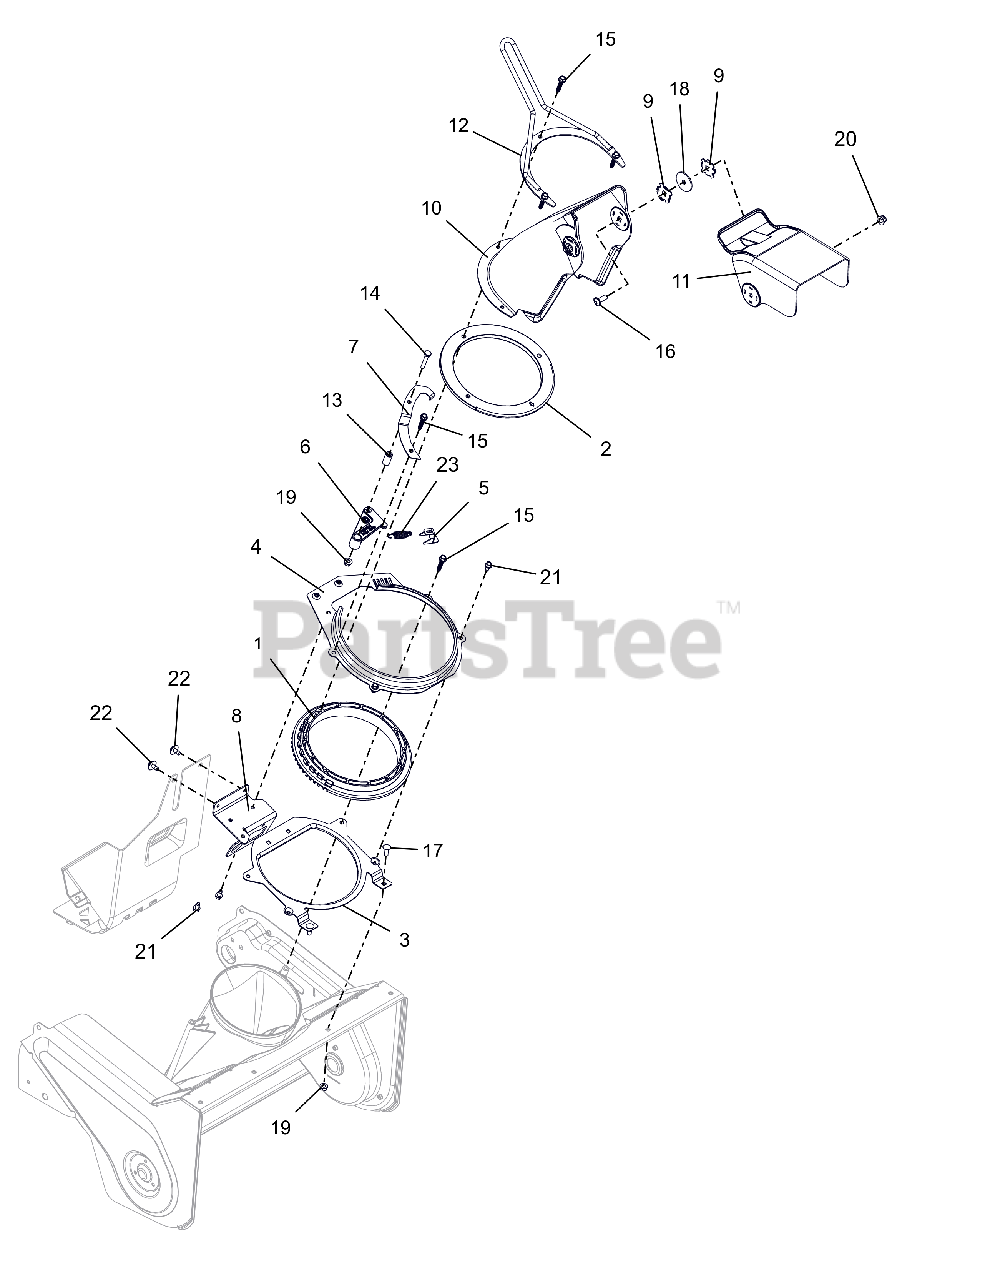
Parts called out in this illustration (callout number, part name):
1	GEAR, CHUTE RING
2	GUARD, WATER
3	RING, CHUTE MOUNT - LOWER
4	RING, CHUTE MOUNT - UPPER
5	BRKT, SPRG
6	ARM, PAWL
7	PAWL ARM STOP
8	BRKT, CHUTE ROTATION - REAR
9	PLATE, FRICTION
10	CHUTE,DISCHARGE - SINGLE STAGE
11	CAP, CHUTE - W/DECAL
12	HANDLE, ROTATION - MANUAL
13	BSHG, SLV .265X.505X.995
14	@BLT-HEX .25-20X1.50 GR5 YWZC
15	SCR-TAP .25-10X1.25 HWH YWZC
16	SCR,BTN-FLG .31-18X0.875
17	@BLT-RDHDSQNK .25-20X.75 G5YZ
18	WSHR,FRICTION-.332X1.525X.094
19	@NUT-LK-TOP-FLG .25-20 YWZC
20	@NUT-LK-NYL-FLG .31-18 YWZC
21	SCR-TAP .25-20X.50 HWH TR YWZ
22	SCR-TAP .25-20X.50 LGHWH TR YZ
23	SPRG, TENSION .052X.520X1.74
